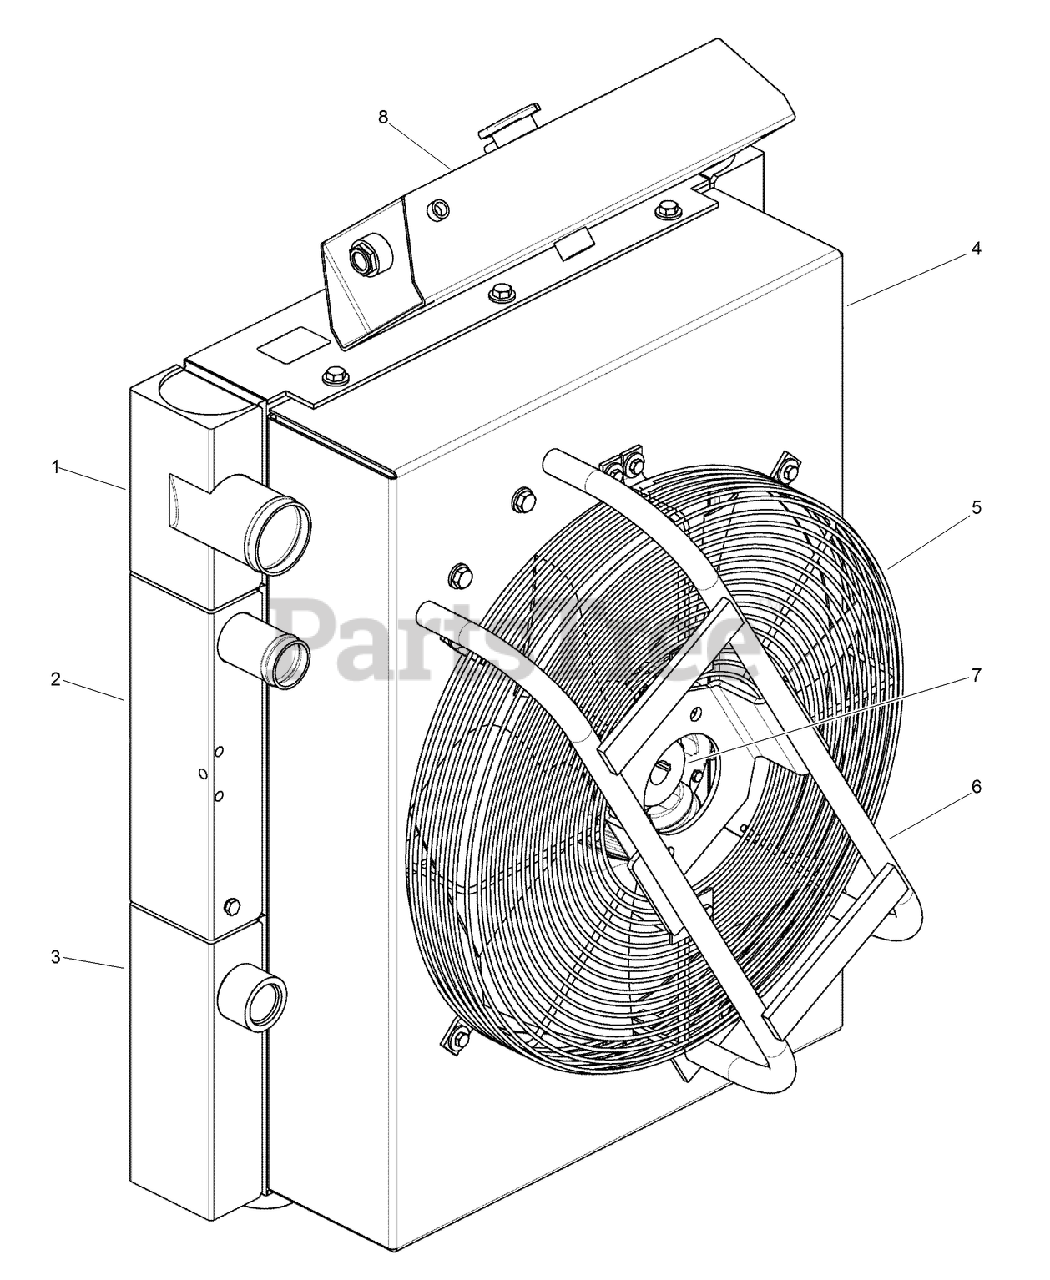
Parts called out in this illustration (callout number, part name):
1	COOLER - Charge Air
2	COOLER - Radiator
3	COOLER - Hydraulic Oil
4	ASSEMBLY - Shroud
5	GUARD-FAN, 22 INCH
6	BRACKET-MOUNTING
7	OBS FAN-COOLING, 22IN
8	TANK-FILL/SURGE
